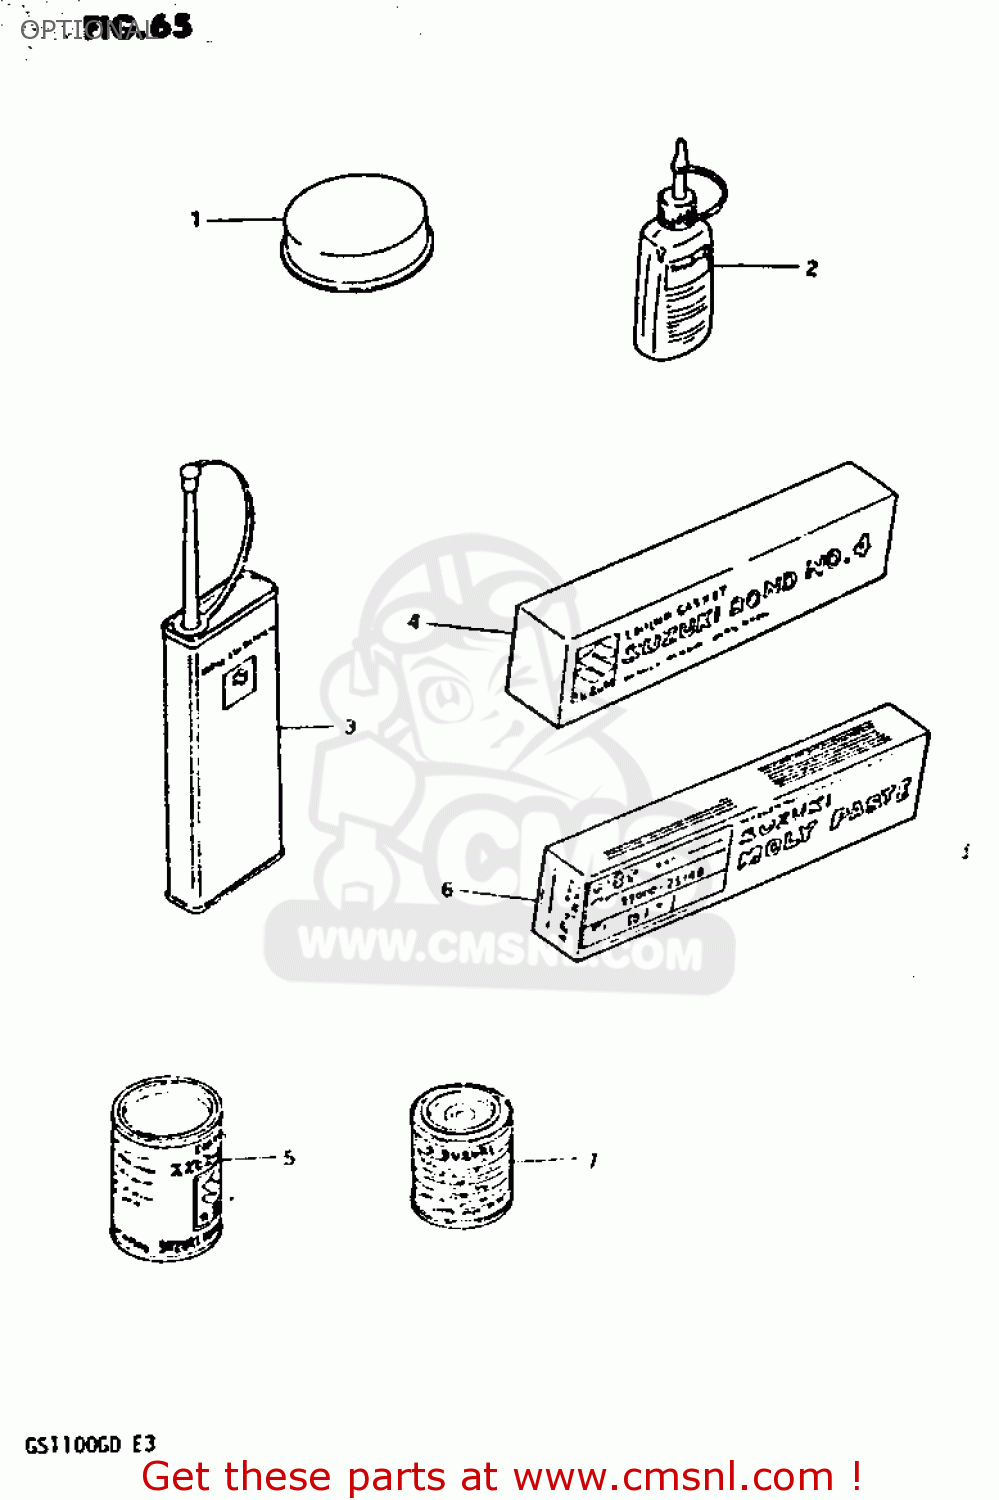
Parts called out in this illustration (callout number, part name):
1	GREASE,PBC FOR BRK PAD 20G
2	THREAD LOCK NO.1342
3	THREAD LOCK NO.1401 CLEAR 200G
4	LIQUID GASKET 1
5	GREASE(C)EP2 LITHIUM 150G
6	SUZUKI MOLY PASTE
7	PAINT,BLACK
